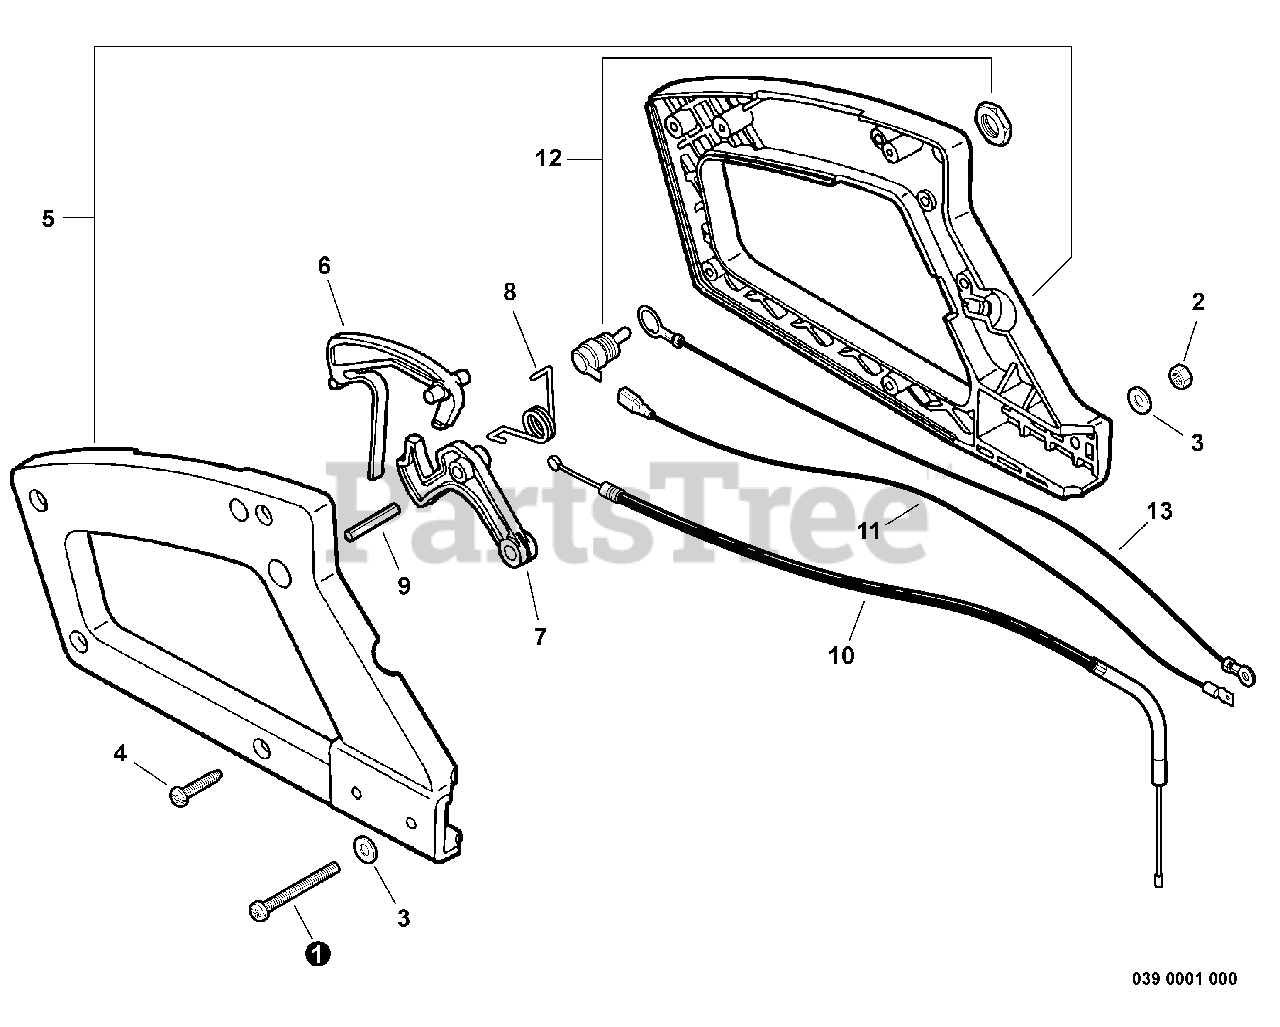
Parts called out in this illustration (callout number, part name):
1	SCREW 5×47
2	NUT, LOCK M5
3	WASHER, FLAT 5.5×10×0.8
4	SCREW 4×16
5	HANDLE SET, REAR
6	LOCKOUT, THROTTLE
7	TRIGGER, THROTTLE
8	SPRING, THROTTLE RETURN
9	PIN, SPRING Ø5×25 MM
10	CABLE, THROTTLE
11	LEAD - IGNITION
12	SWITCH, ON-OFF
13	LEAD - GROUND
